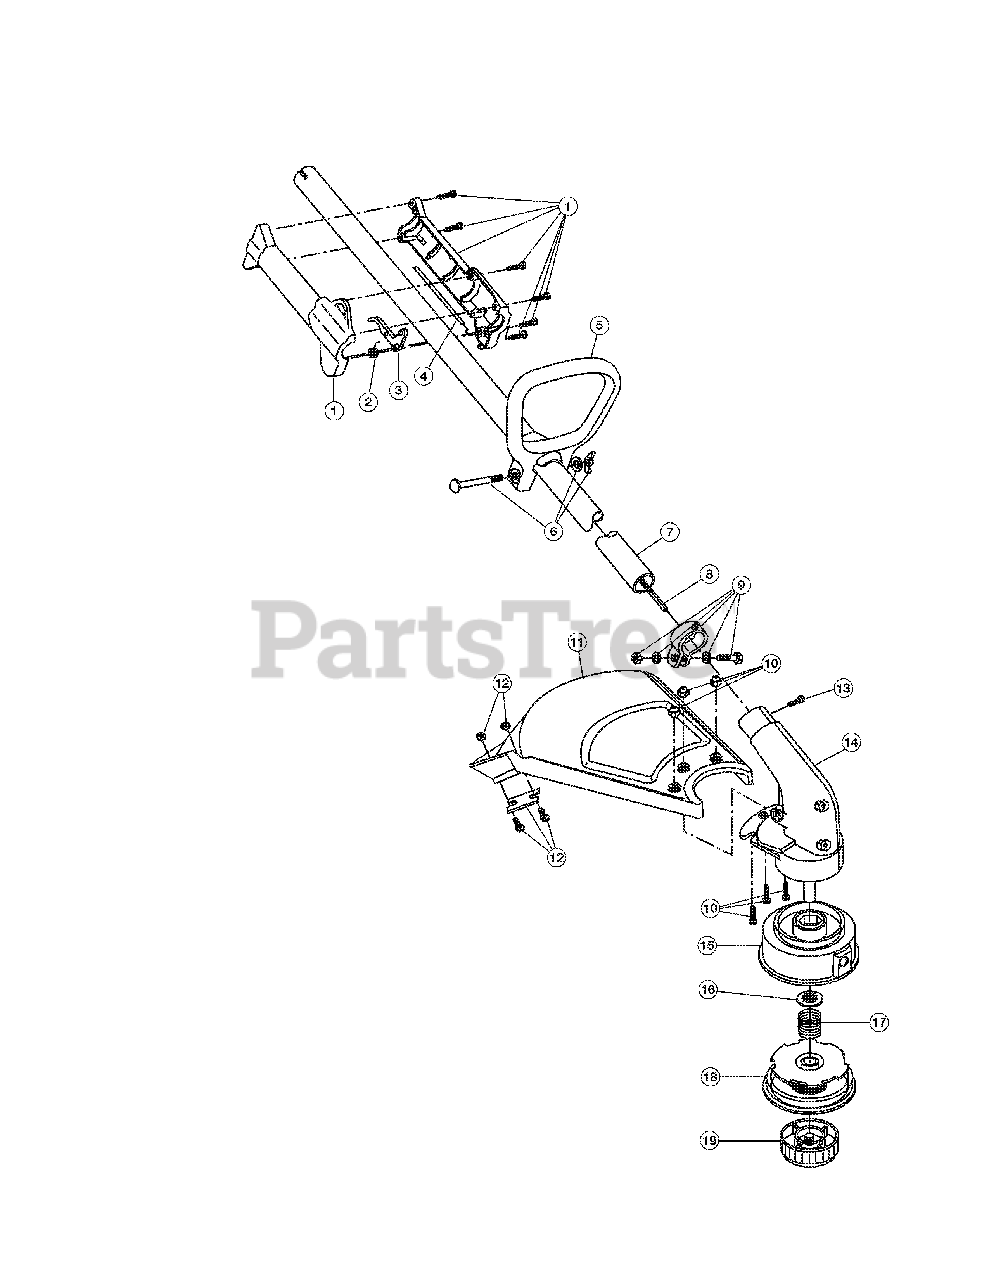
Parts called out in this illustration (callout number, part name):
1	Throttle Housing Assembly (includes 2 & 3)
2	Throttle Trigger Spring
3	Throttle Trigger
4	Throttle Cable
5	D-Handle Assembly (includes 6)
6	D-Handle Hardware
7	Drive Shaft Housing Assembly (includes 8)
8	Flexible Drive Shaft
9	Lower Clamp Assembly (includes 13)
10	Guard Mounting Hardware
11	Guard Assembly (includes 12)
12	Blade Assembly
13	Anti-Rotation Screw
14	Gearbox Assembly (includes 15 & 16)
15	Outer Spool Assembly (includes 16)
16	Retainer
18	Inner Reel
19	Bump Head Knob Assembly
